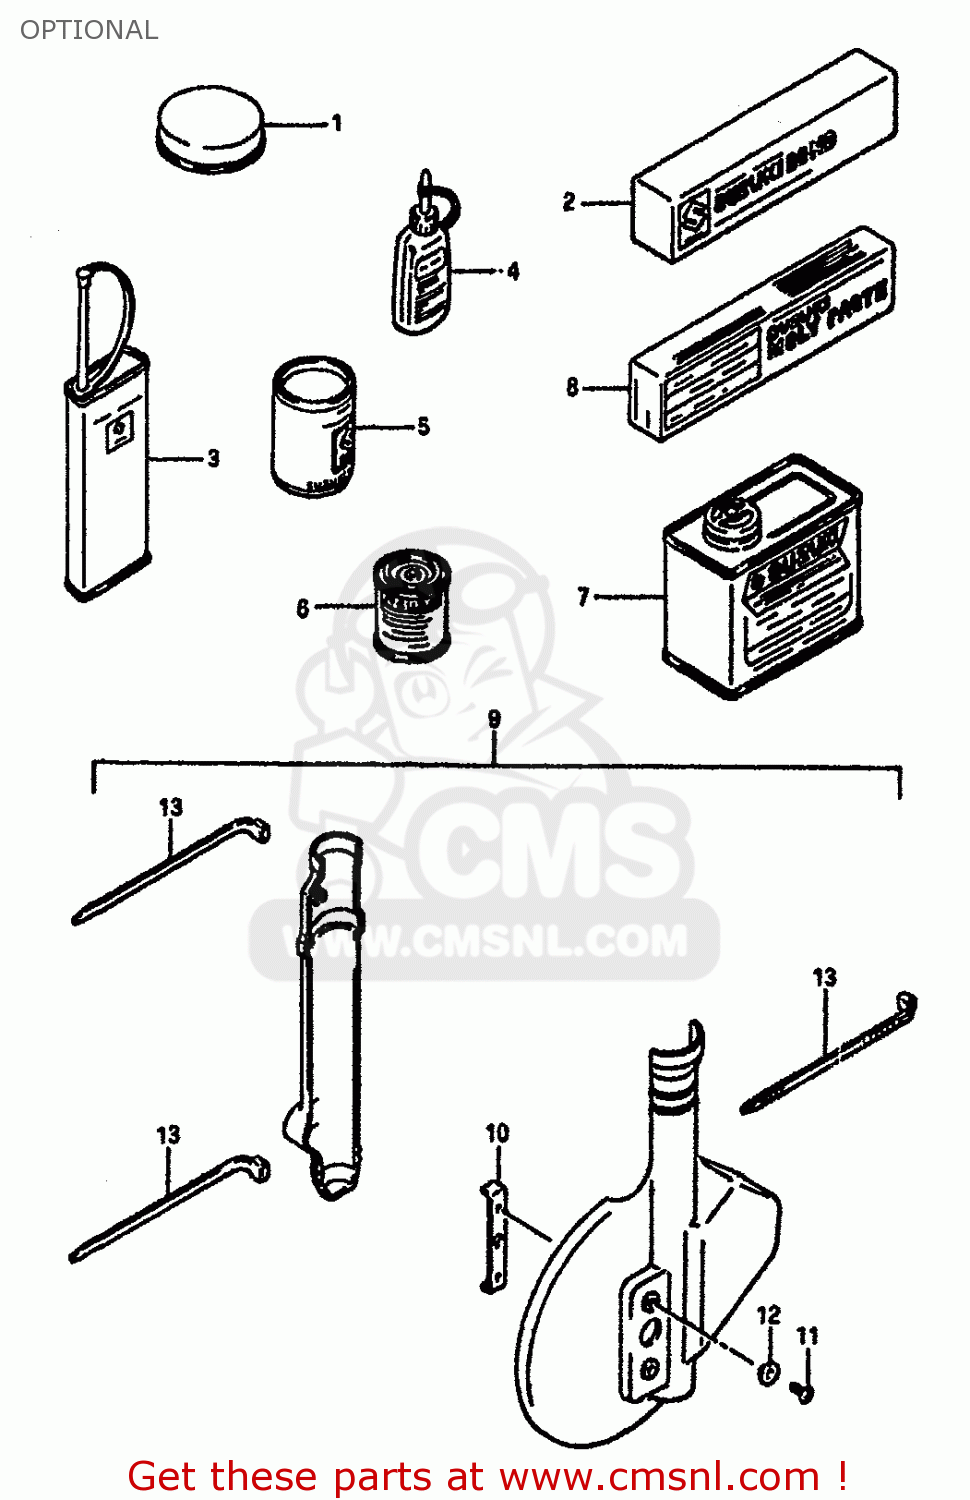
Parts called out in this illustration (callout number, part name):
1	TUBE REPARING TOOL
2	LIQUID GSKT NO.1207B 100G BLK
3	THREAD LOCK NO.1401 CLEAR 200G
4	THREAD LOCK NO.1342
5	GREASE(C)EP2 LITHIUM 150G
6	PAINT,BLACK
7	PAINT (BLACK)
8	SUZUKI MOLY PASTE
9	PROTECTOR SET, FRONT FORK (WHITE)
10	PLATE, PROTECTOR
11	SCREW 6X12
12	WASHER
13	CLAMP
